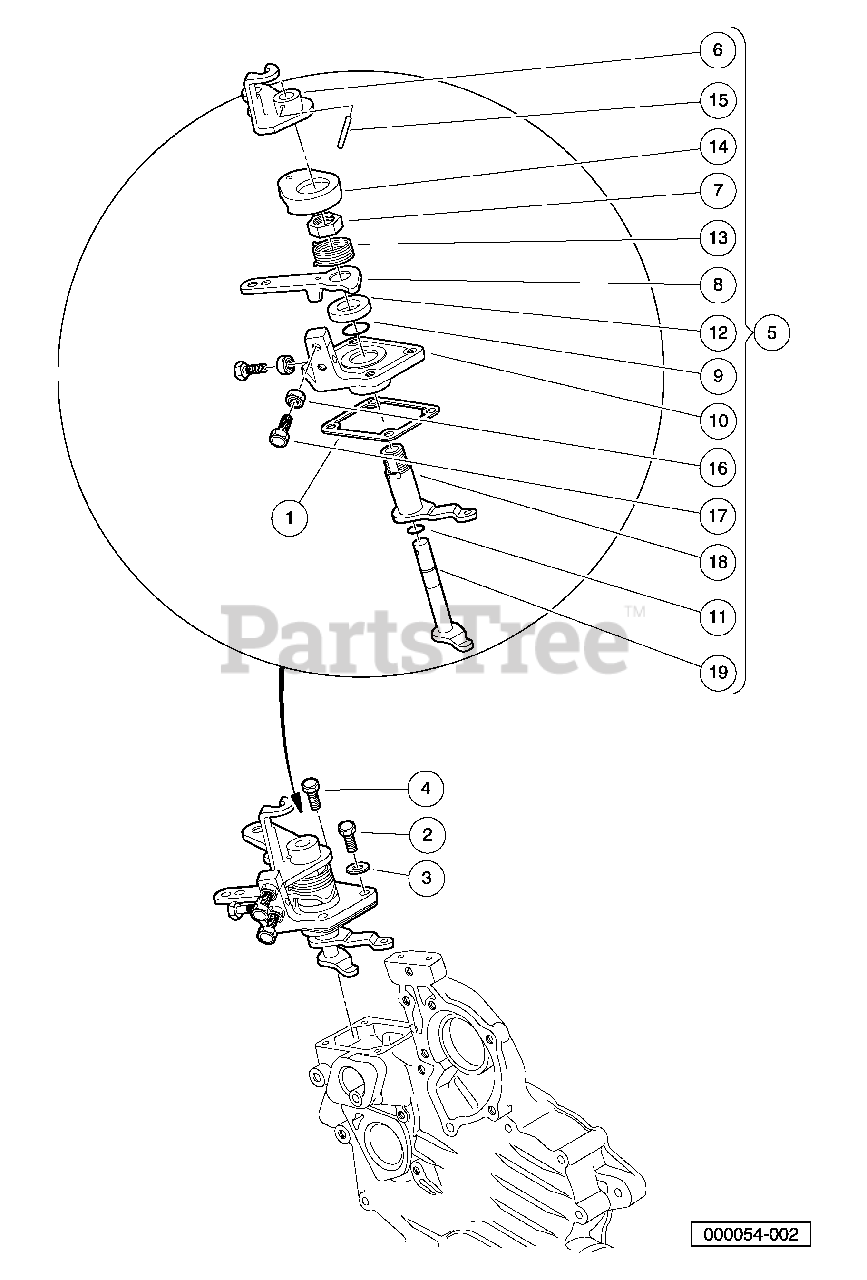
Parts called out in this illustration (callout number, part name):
1	Gasket, Control Plate
2	Bolt, M6 X 1 X 30
3	Gasket, 6 X 10
4	Bolt, D722 Intake Manfld Lower.
5	Assembly, Speed Plate
6	Lever, Engine Stop
7	Nut, Speed Control
8	Lever, Speed Control
9	O Ring, 19 X 16
10	Plate, Speed Control
11	O Ring, 9 X 7
12	Collar, Lever.
13	Spring, Return
14	Cap, Speed Cntrl Plate Rtrn
15	Pin, Spring, Speed Plate
16	Nut, Speed Control
17	Bolt, Speed Control
18	Lever, Governor
19	Shaft, Governor Lever
